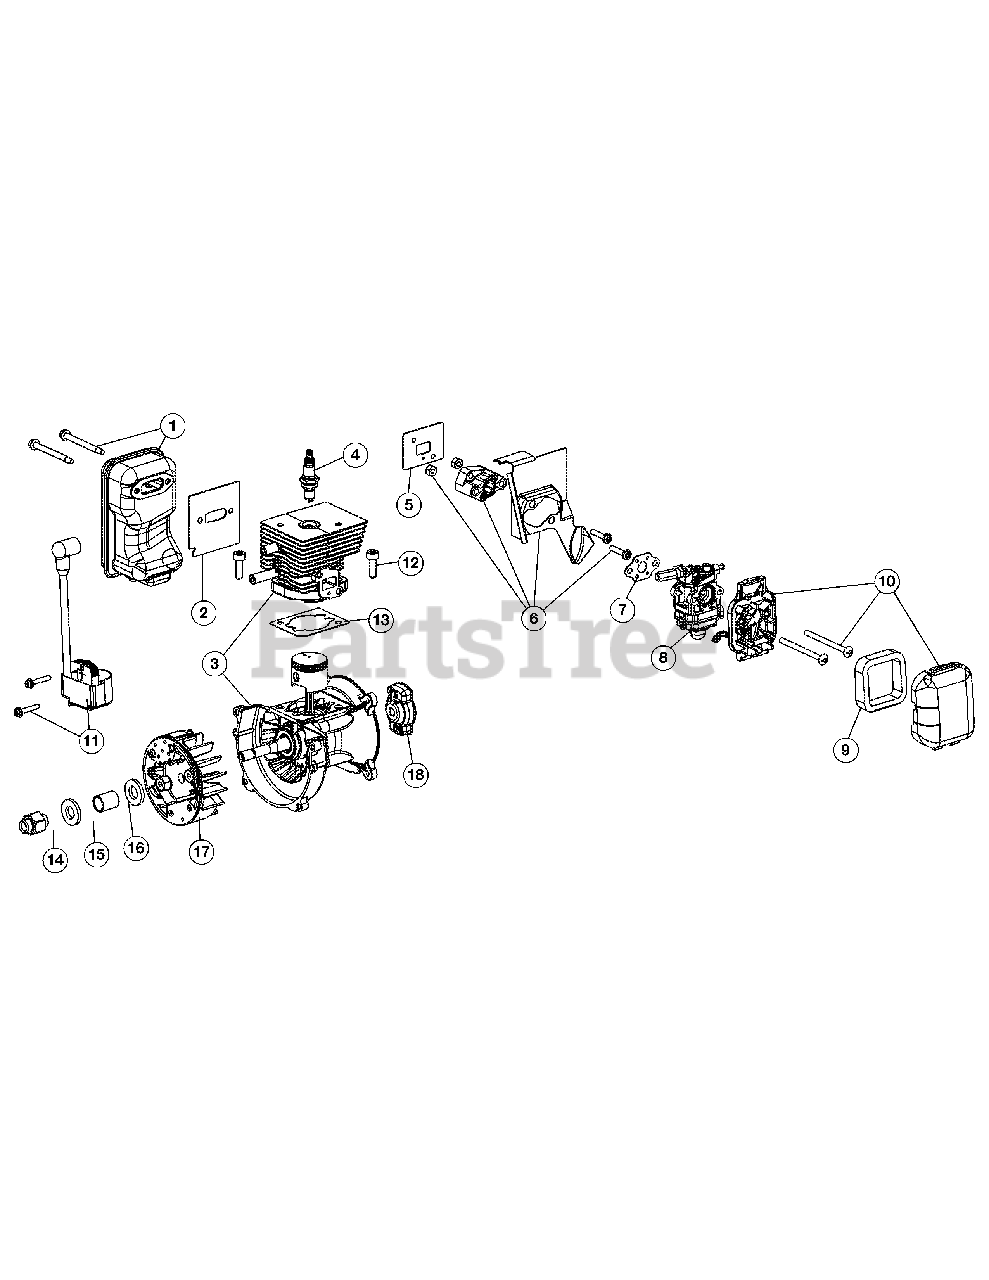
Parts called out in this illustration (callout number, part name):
1	Muffler Assembly
2	Muffler Gasket
3	Shortblock Assembly
4	Spark Plug
5	Insulator Gasket
6	Insulator Assembly
7	Carburetor Gasket
8	Carburetor Assembly
9	Air Filter
10	Aircleaner Assembly
11	Module Assembly
12	Screw
13	Cylinder Gasket
14	Flywheel Adapter
15	Washer
16	Bushing
17	Flywheel Assembly
18	Pawl Assembly
